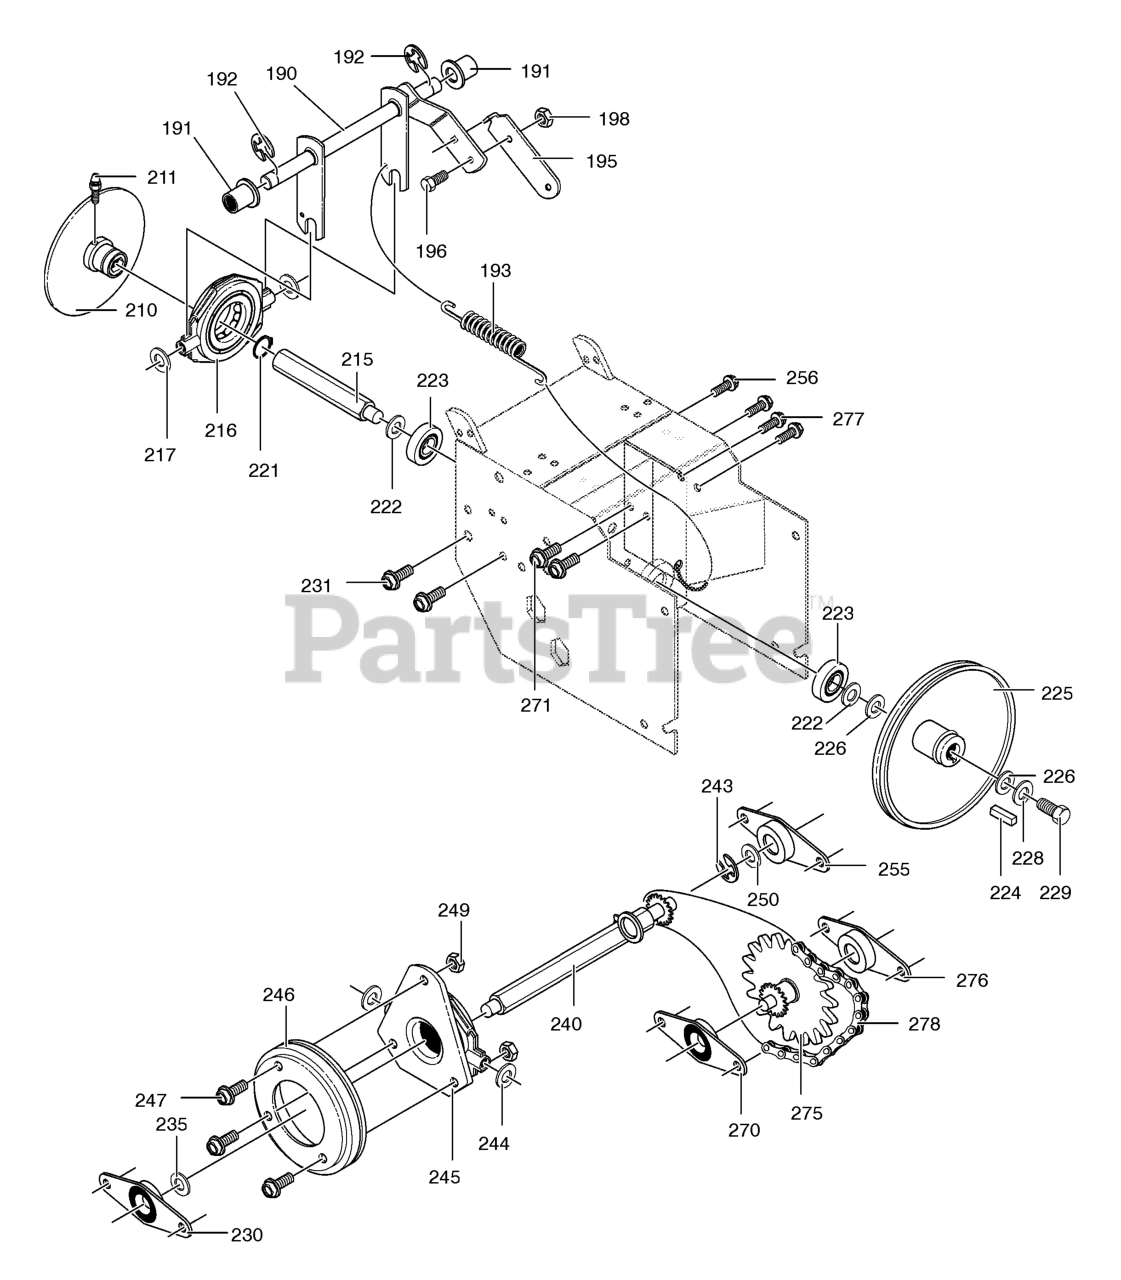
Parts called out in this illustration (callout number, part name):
190	LEVER, ASSY TRACTION CLUTCH
191	BEARING, FLANGE
192	RING, RET E
193	SPRING, RETURN
195	LEVER, SPRING
196	SCREW, 1/4-20X .63
198	NUT, 1/4-20 REGHEXCTRLK
210	DISC, ASSY
211	ZERK, GREASE
215	SHAFT, HEX TRACTION
216	BEARING, TRUNION
217	FLATWASHER, .53 X1.00X.063
221	RING, RETEX
222	FLATWASHER, .680X1.12X.060
223	BEARING, BALL
224	KEY, SQUARE
225	PULLEY, V3L 6.50X .56
226	WASHER, WAVE
227	FLATWASHER, .281X1.00X.063
228	WASHER, SPLIT .26X.50X.06
229	SCREW, 1/4-20X .75 HHC
230	BEARING & RETAINER
231	SCREW, 5/16-18 x 0.50
235	WASHER,.502X .75X.0605
240	HEX, ASSY #40-8T W/PBRG
243	RING, RETEX
244	FLATWASHER, .53 X1.00X.063
245	BEARING, TRUNION
246	WHEEL, ASSY FRICTION
247	SCREW, 1/4-20X .63
249	NUT, 1/4-20 HEXKEPS
250	WASHER,.502X .75X.0605
255	BEARING & RETAINER
256	SCREW, 5/16-18 x 0.50
270	BEARING & RETAINER
271	SCREW, 5/16-18 x 0.50
275	JACK, ASSY #41-36/7
276	BEARING & RETAINER
277	SCREW
278	CHAIN ROLLER
